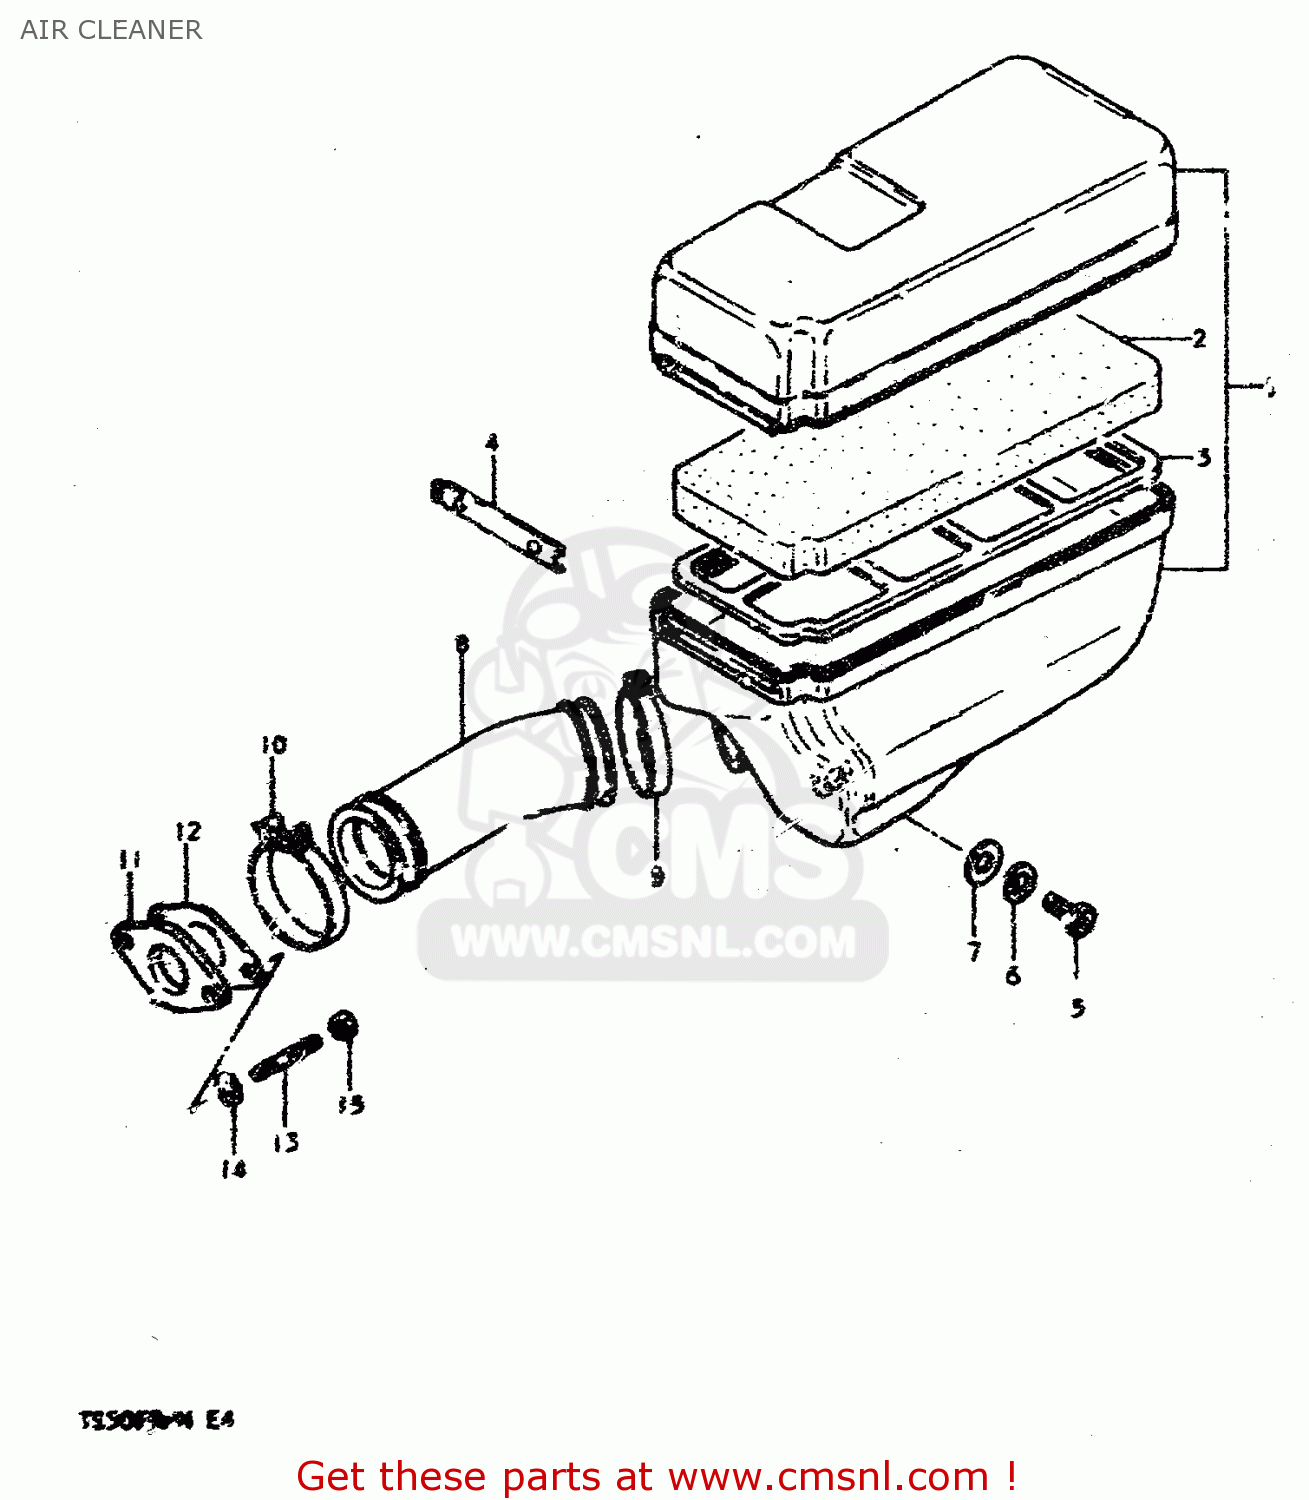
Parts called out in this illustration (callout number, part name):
1	CLEANER ASSY,A
2	FILTER
3	HOLDER
4	SLIDER
5	SCREW
6	LOCK WASHER
7	WASHER
8	TUBE,AIR CLEANER OUTLET
9	CLAMP
10	CLAMP
11	INSULATOR,CARBURETOR
12	GASKET,CARBURETOR (MCA)
13	STUD BOLT
14	WASHER
15	NUT
